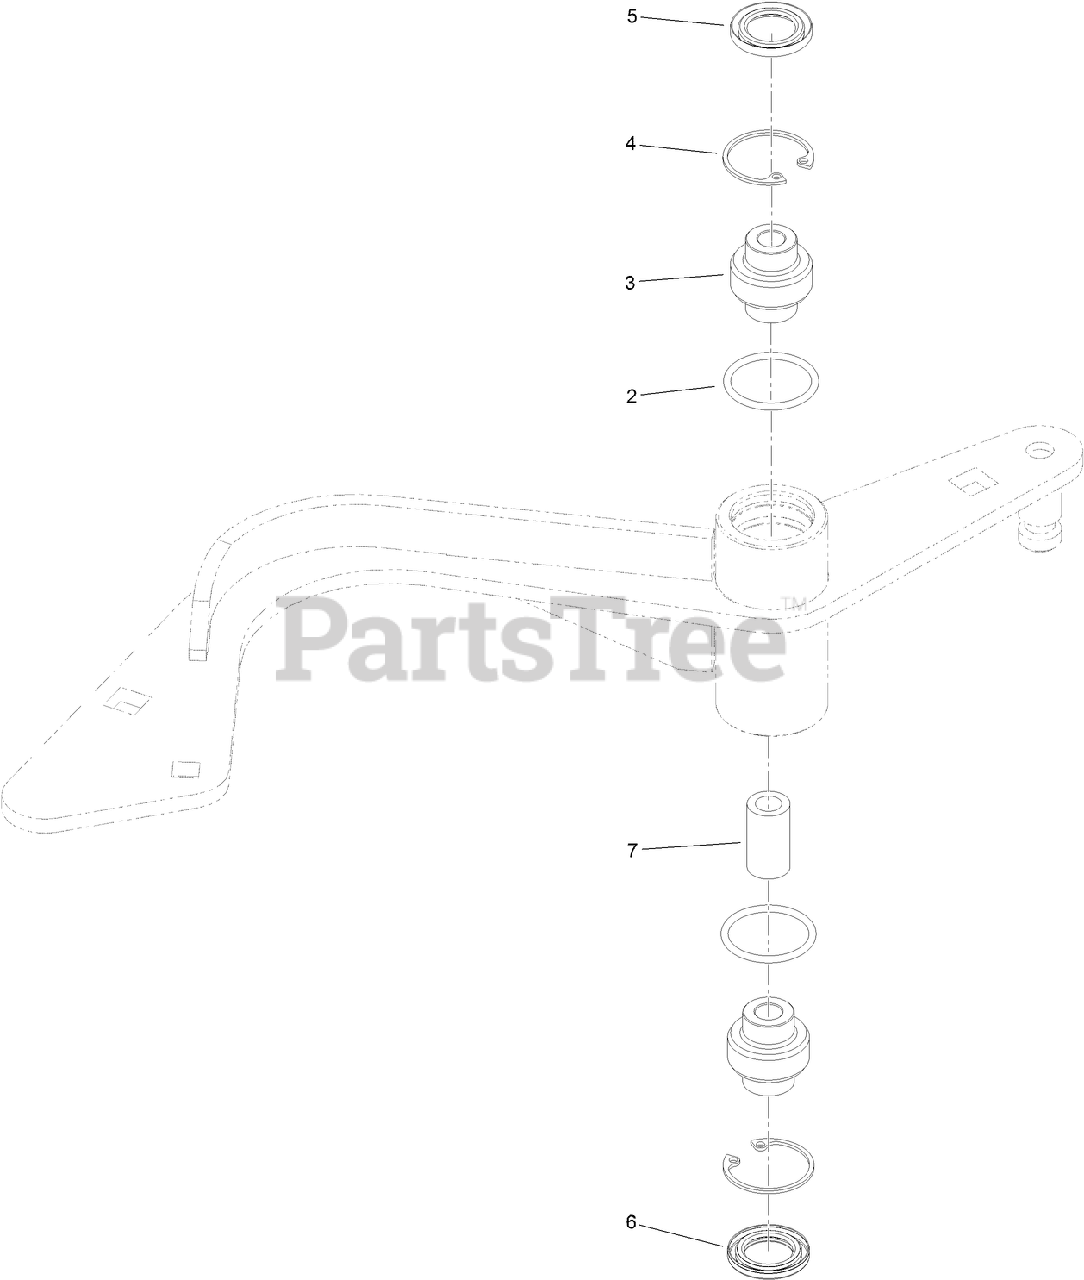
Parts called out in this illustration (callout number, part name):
2	O-RING
3	BEARING-SPHERICAL
4	RING-SNAP
5	SEAL-LIP, SINGLE
6	Seal-Lip, Double
7	SPACER
